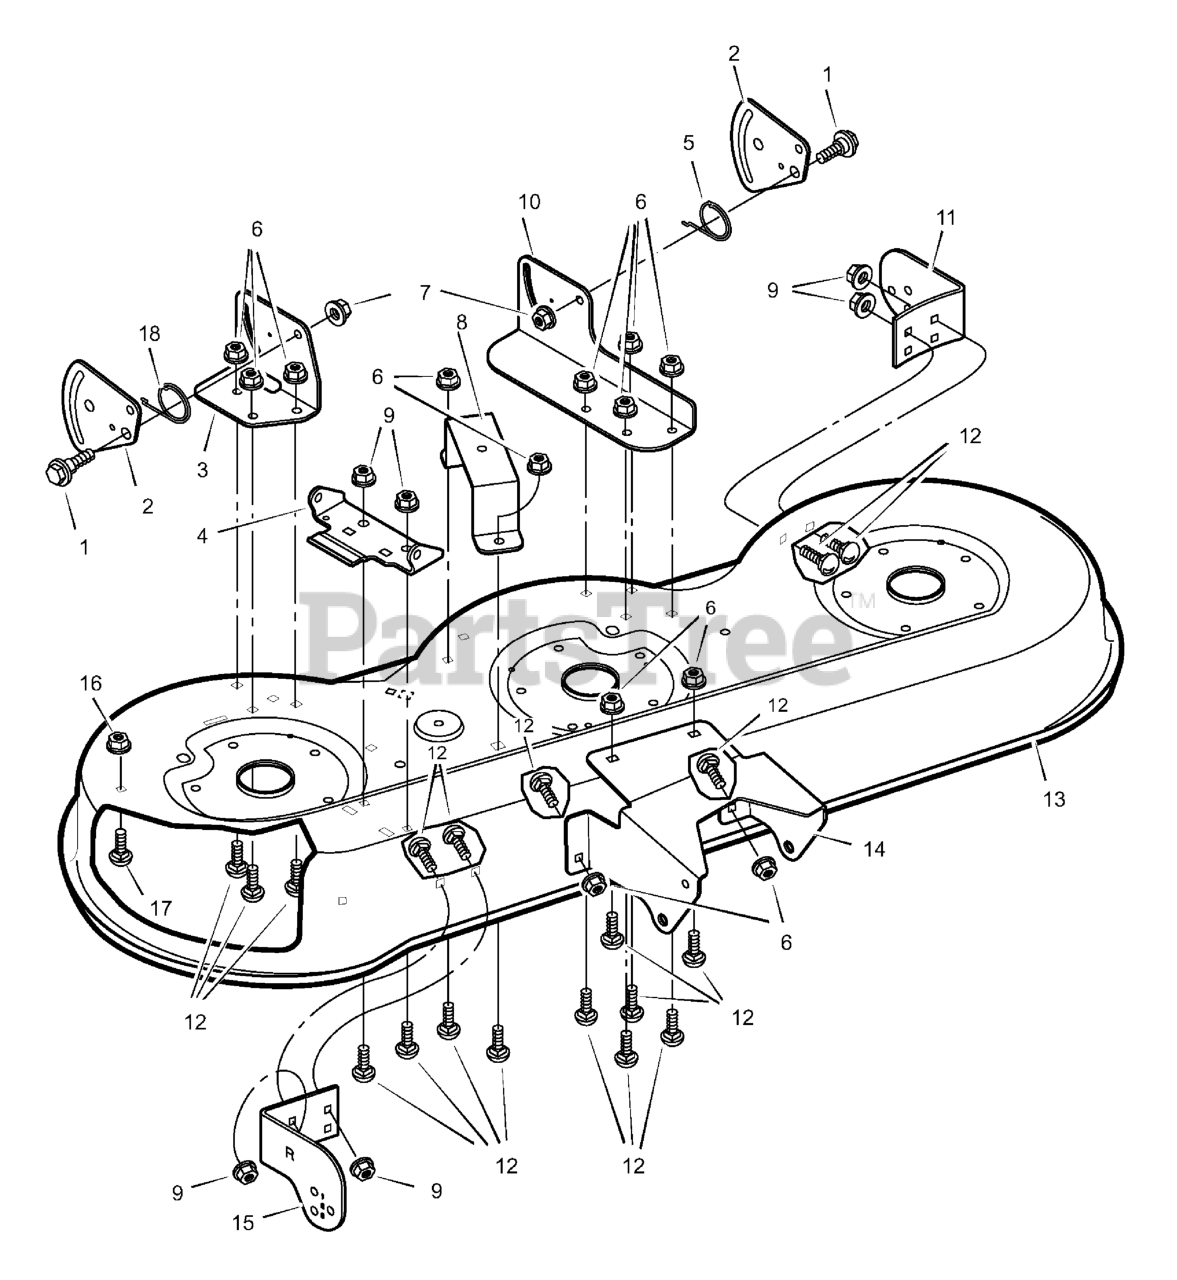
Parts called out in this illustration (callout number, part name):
1	Bolt, Shoulder
2	Plate, Suspension
3	Bracket, Right Rear
4	Bracket, Hinge
5	Spring, Left
6	Nut, Flange
7	Nut, Flange
8	Bracket, Bell Crank
9	Nut, Flange
10	Bracket, Left Lifter
11	Bracket, Left Gauge Wheel
12	Bolt, Carriage
13	Housing, Blade
14	Bracket, Front Deck
15	Bracket, Right Gauge Wheel
16	Retainer
17	Bolt, Carriage
18	Spring, Right
